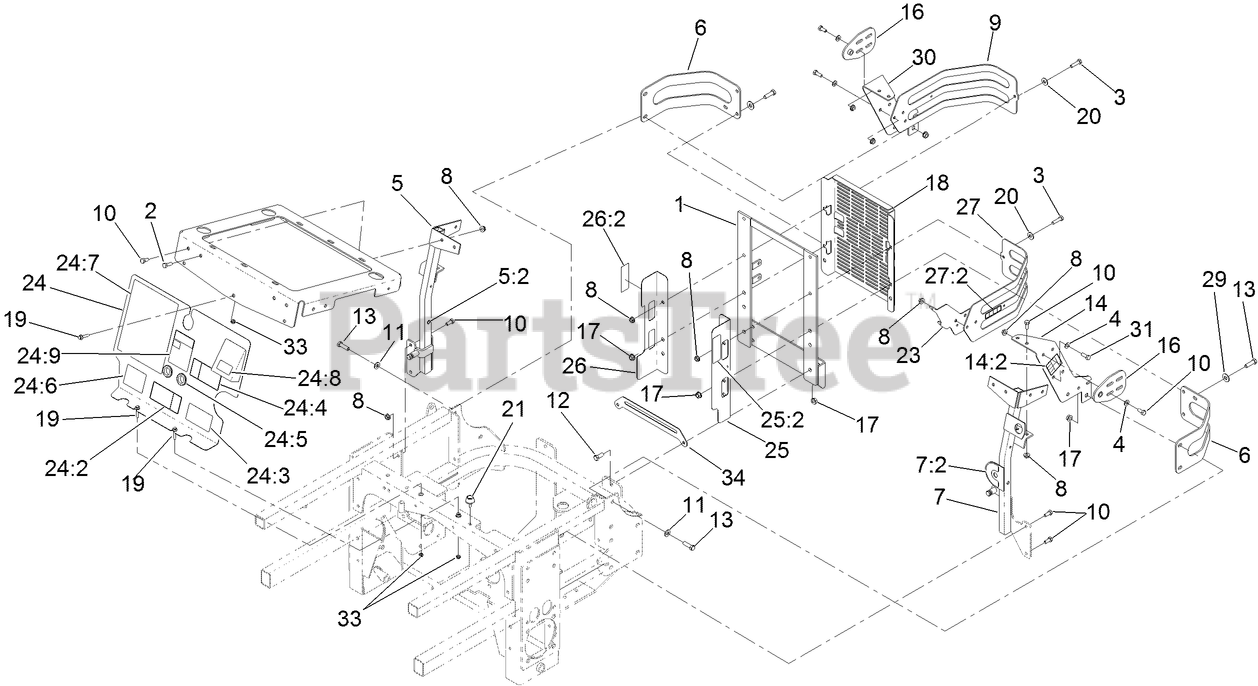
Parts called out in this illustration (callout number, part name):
1	SUPPORT-RADIATOR, REAR
2	SCREW-HH
3	SCREW-HH
4	WASHER-PLAIN
5	RH RADIATOR BRACE ASM
5:2	NUT-CLINCH
6	GUARD-LOWER, REAR
7	LH RADIATOR BRACE ASM
7:2	DECAL-FUEL VALVE
8	NUT-HF
9	GUARD-UPPER, REAR
10	SCREW-HH
11	WASHER-FLAT
12	SCREW-HH
13	SCREW-HH
14	LH SUPPORT BRACKET ASM
14:2	DECAL-FUSE
16	PLATE-PIVOT, HOOD
17	NUT-HHF, WHIZ
18	SHIELD-COOLER
19	SCREW-HHF
20	WASHER-FLAT
21	BUMPER-RUBBER
23	BRACKET-RELAY, FUSE
24	FRONT SHIELD ASM
24:2	DECAL-DANGER, ROTATING DEVICES
24:3	DECAL-HYDRO BELT ROUTING
24:4	DECAL- WARNING, BUZZER
24:5	GROMMET-RUBBER
24:6	DECAL-CLUTCH BELT ROUTING
24:7	DECAL-CHECK SERVICE
24:8	DECAL-CAUTION
24:9	DECAL-COOLANT
25	GUARD-FAN, LH (CE)
25:2	DECAL-DANGER
26	GUARD-FAN, RH (CE)
26:2	DECAL-DANGER
27	GUARD-UPPER REAR W/DECAL
27:2	DECAL-RELAY
29	WASHER-FLAT
30	BRACKET-SUPPORT, RH
31	SCREW-HH
33	NUT-LOCK, NI
34	SHIELD-FAN
